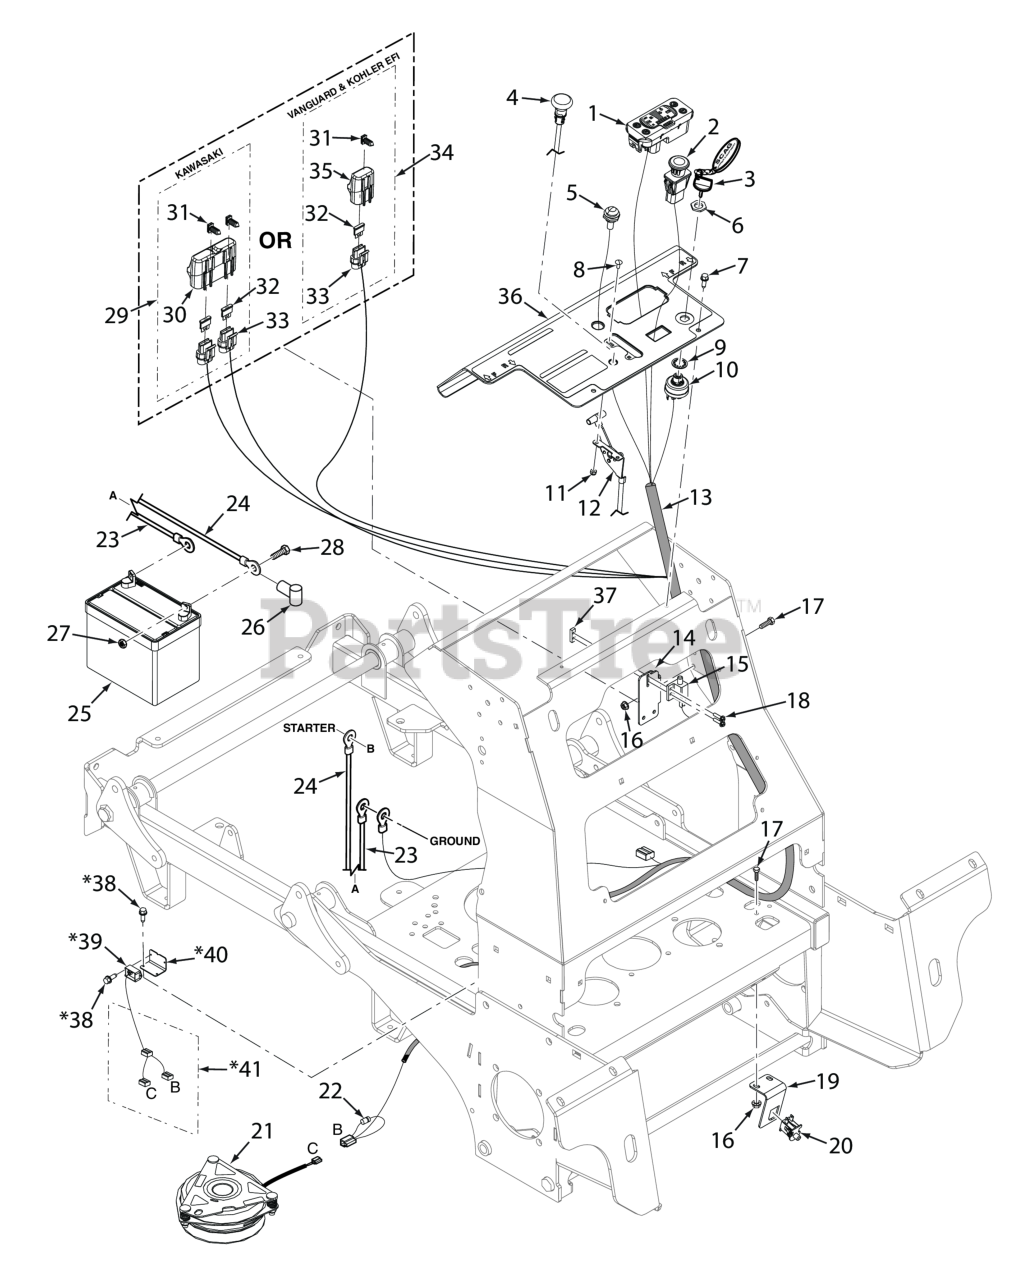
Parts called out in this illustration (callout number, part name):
1	Tiger Eye, Cluster Gauge
2	Switch, PTO - 10 Amp
3	Key, Assembly w/Fob
4	Choke Control (excludes EFI models)
5	Indicator Light, Glow Plugs (Includes Mounting Hardware)
6	Nut, 5/8-32 Special
7	Screw, Self-Tapping 1/4-20 x 3/4
8	Bolt, Carriage #10-24 x 1/2"
9	LOCK WASHER, 5/8" INTERNAL TOOTH
10	KEY SWITCH(INCLUDES MOUNTING HARDWARE)
11	Nut, Elastic Stop #10-24
12	Throttle Control, SVR
13	Wire Harness, SVRII-EFI
14	Bracket, Neutral Switch
15	Switch, Interlock, Park Brake Normally Open
16	NUT, 1/4-20 SERRATED FLANGE HEX HEAD
17	BOLT, HEX HEAD, 1/4-20 X 3/4 GR.5
18	Screw, Hex-Slotted Washer Head #10 32 x 3/4"
19	Switch Bracket, Operator Presence
20	SWITCH, NEUTRAL INTERLOCK
21	Clutch w/Tag GT2.5-FE02 (48 / 52)
22	Diode, 600V 6 Amp
23	Battery Cable, 39" Black (26EFI) - Kohler
24	Battery Cable, 44" Red w/Braid (26EFI) - Kohler
25	Battery, 350 CCA (not available through Scag)
26	RUBBER BOOT
27	Nut, 1/4 - 20 Hex
28	BOLT, HEX HEAD, 1/4-20 X 3/4 GR.5
29	Double Fuse Assy.
30	Cover, Sealed Double
31	Clip, Fuse Holder
32	FUSE, 20 AMP BLADE TYPE AUTOMOTIVE
33	Fuse Holder Assembly
34	Single Fuse Assy., Excluding Fuse
35	Cover, Sealed Single
36	Control Panel w/Decal
37	Plate, Threaded
38	Screw, #10-32 x .563 Shakeproof
39	Soft Start Module, Clutch
40	Mounting Bracket, Soft Start Module
41	Wire Harness, Clutch Soft Start
